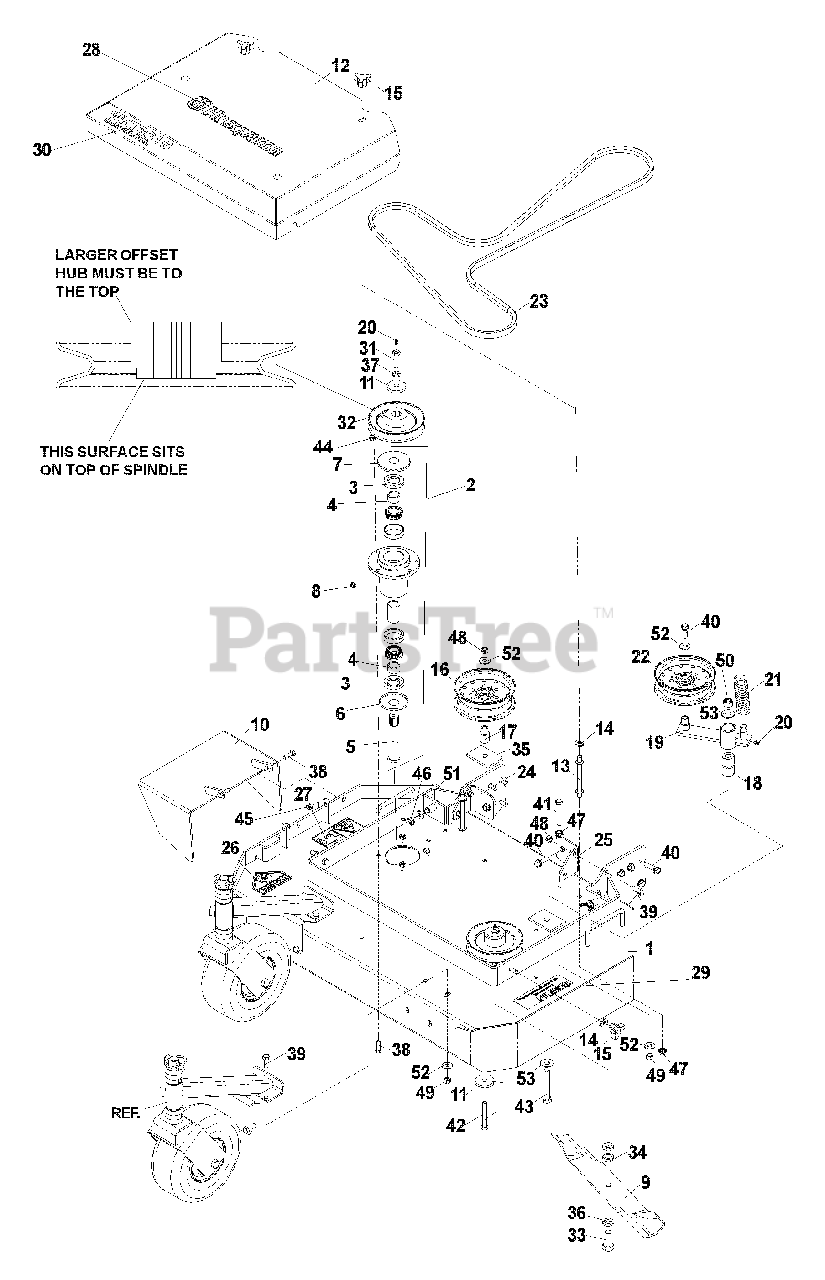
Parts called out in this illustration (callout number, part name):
1	36" DECK W/DECALS
2	SPINDLE ASSEMBLY, COMPLETE
3	SHAFT SEAL
4	TOP & BOTTOM SPACERS
5	SPINDLE
6	DUST CUP, BOTTOM
7	DUST CUP, TOP
8	GREASE POPET
9	BLADE, 18"
10	DEFLECTOR CHUTE
11	HEAVY WASHER
12	SHIELD, BELT, 36"
13	SPACER, SHIELD
14	WASHER, 3/8, SEALING
15	KNOB, 3-PRONG
16	IDLER PULLEY (TALL)
17	BUSHING, IDLER
18	BUSHING, PIVOT
20	ZERK
22	IDLER PULLEY
23	BELT, DECK
24	DECK SLIDE, RIGHT
25	DECK SLIDE, LEFT
26	DECAL, CPSC
27	DECAL, EURO SEVERING
28	DECAL, HUSQVARNA
29	DECAL, NASCAR
30	DECAL, WHT 3615
31	HCS, 7/16-20 X 1 1/2, GR5
32	PULLEY
33	HCS, 5/8-18 X 1 1/2, GR5
34	SPACER, BLADE
36	LOCKWASHER, 5/8
37	LOCKWASHER, 7/16
38	HCS, 5/16-18 X 1, GR5
39	HCS, 3/8-16 X 1, GR5
40	HCS, 3/8-16 X 1, GR5
41	HCS, 3/8-16 X 2 1/2, GR5
42	HCS, 3/8-16 X 2 3/4, GR5
43	HCS, 1/2-13 X 3 1/4, GR5
44	NUT, 5/16C, CENTER LOCK
45	NUT, 5/16C, NYLOC
46	NUT, 5/16C, WINGNUT
48	NUT, 3/8C, CENTER LOCK
49	NUT, 3/8C, NYLOC
50	NUT, 1/2C, NYLOC
51	WASHER, 5/16
52	WASHER, 3/8
53	WASHER, 1/2
